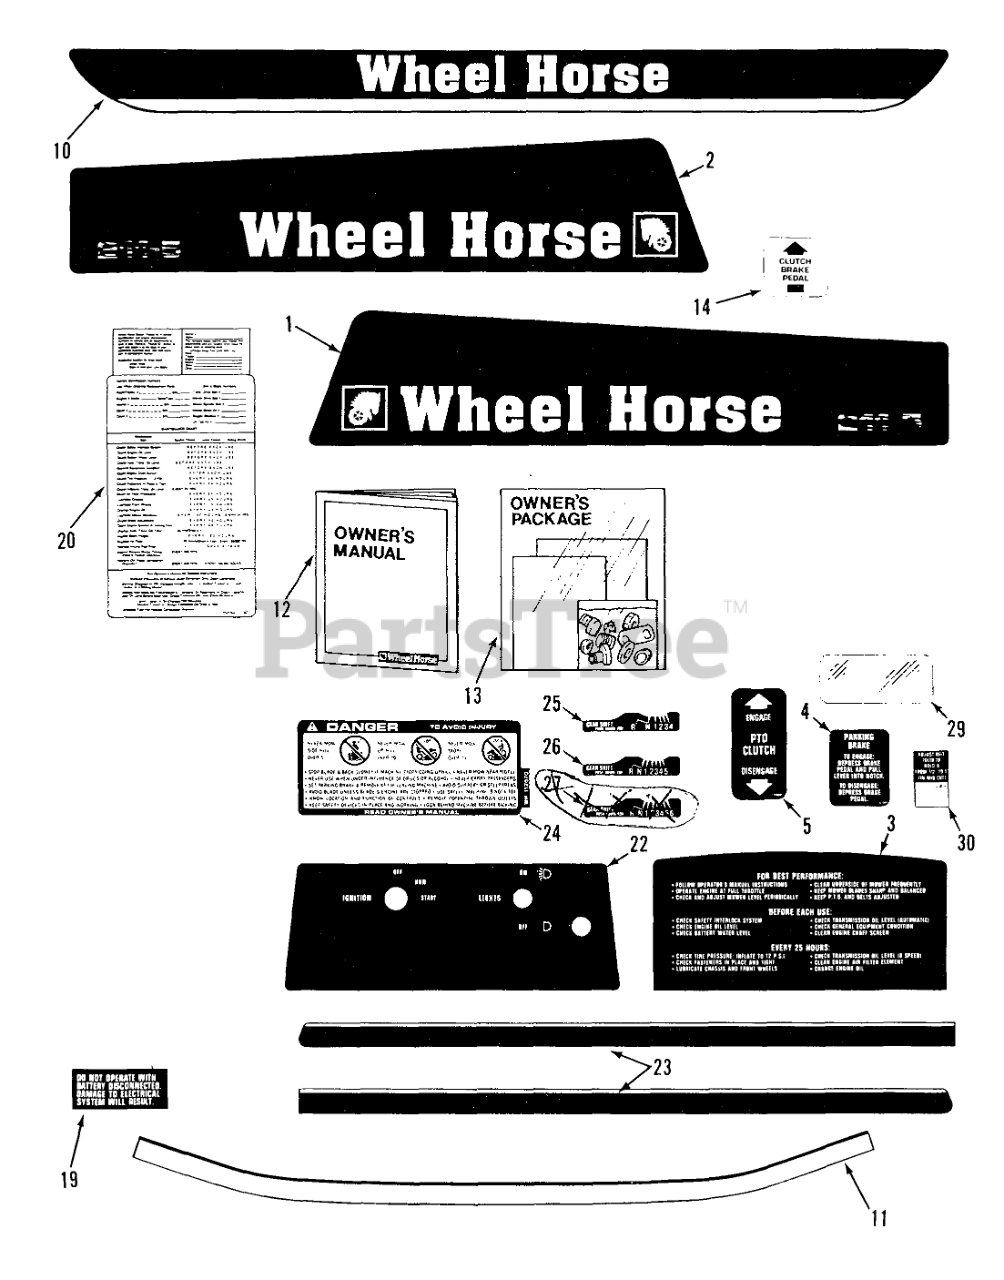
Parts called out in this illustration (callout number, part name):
1	DECAL-HOOD 210-4 R H
2	DECAL-HOOD 210-4 L H
3	DECAL REAR HOOD
4	DECAL PARKING BRAKE
5	DECAL-PTO
10	Decal-Rear Fender
11	DECAL FRONT HOOD
12	Owner-s Manuel-Tractor
13	Screw
14	DECAL CLUTCH & BRAKE
19	DECAL ELECT SYSTEM
20	Decal-Maintenance
21	DECAL-THROTTLE
22	DECAL-BACK PLATE
23	DECAL HOOD STRIPE RH
24	DECAL-DANGER
25	DECAL-SHIFT 4-SPEED
26	DECAL-SHIFT 5-SPEED
29	DECAL-OVERLAY
30	DECAL-PTO BELT ADJ
